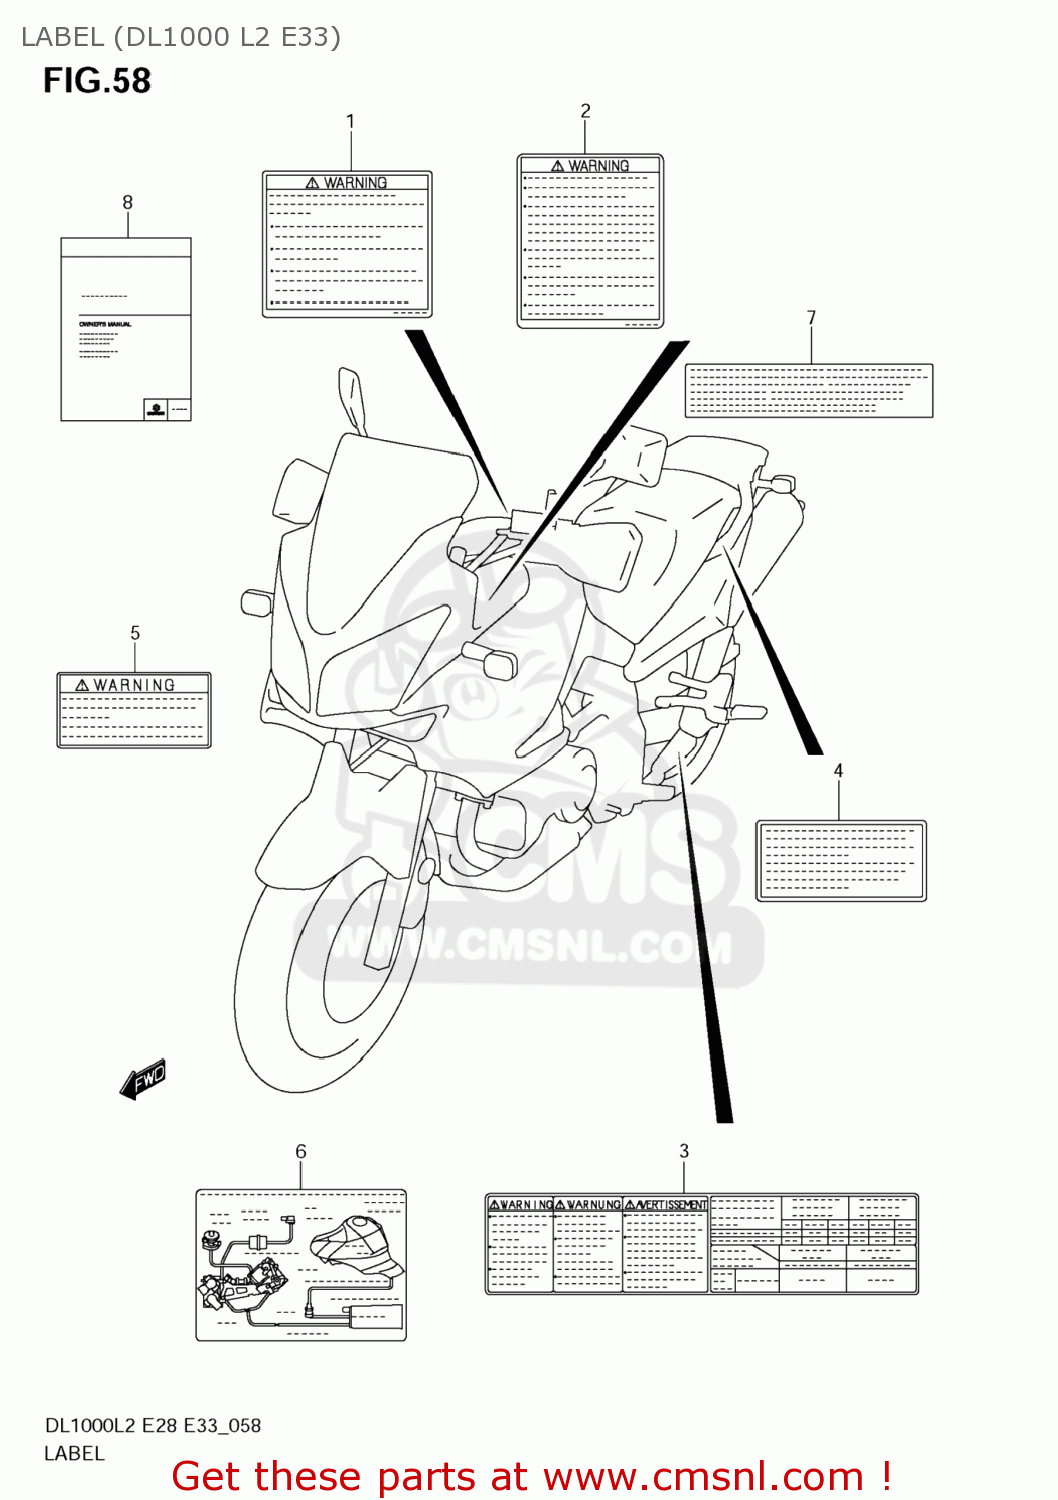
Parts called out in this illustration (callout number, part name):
1	LABEL,GENERAL WARNING
2	LABEL,SCREEN
3	LABEL,TIRE INFORMATION
4	LABEL,MANUAL NOTICE
5	LABEL,WARNING STEERING
6	LABEL,VACUUM HOSE ROUTING
7	LABEL,EPA NOISE
8	MANUAL,OWNER'S
